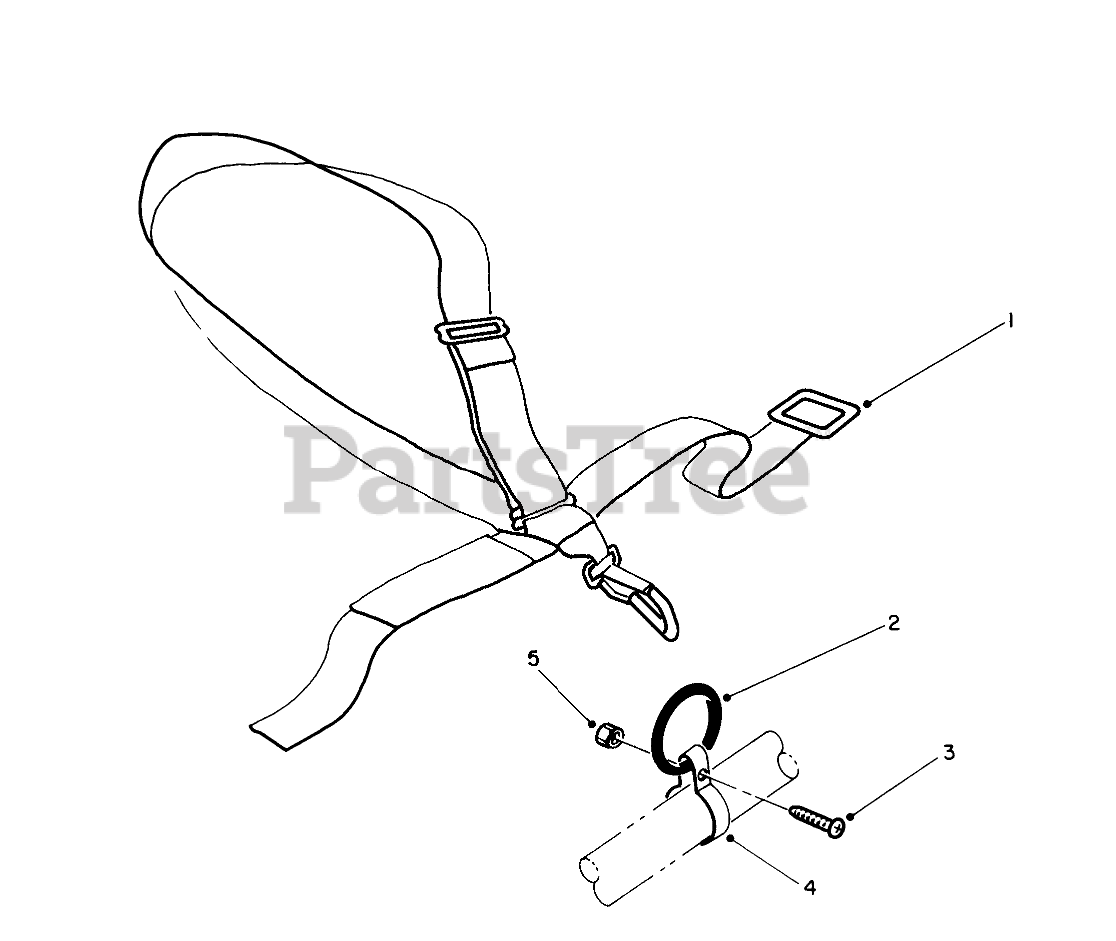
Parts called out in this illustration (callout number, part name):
1	Deluxe Harness
2	RING-HARNESS
3	SCREW-SRH
4	Clamp
5	NUT-LOCK, NI
